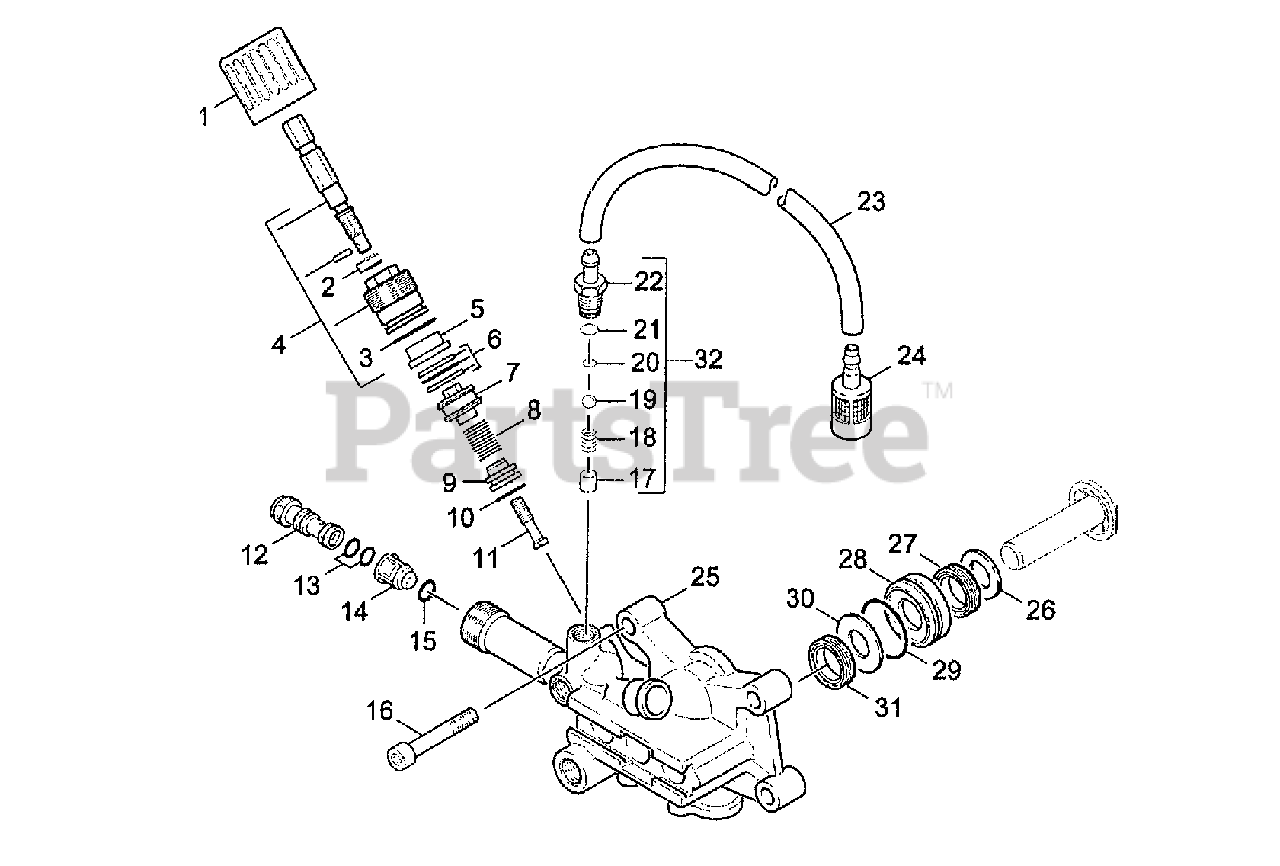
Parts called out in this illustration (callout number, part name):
8	Helical Spring
12	Nozzle Insert
18	Helical Spring
25	Cylinder Head
27	Grooved Ring
31	Grooved Ring
32	Check Valve
